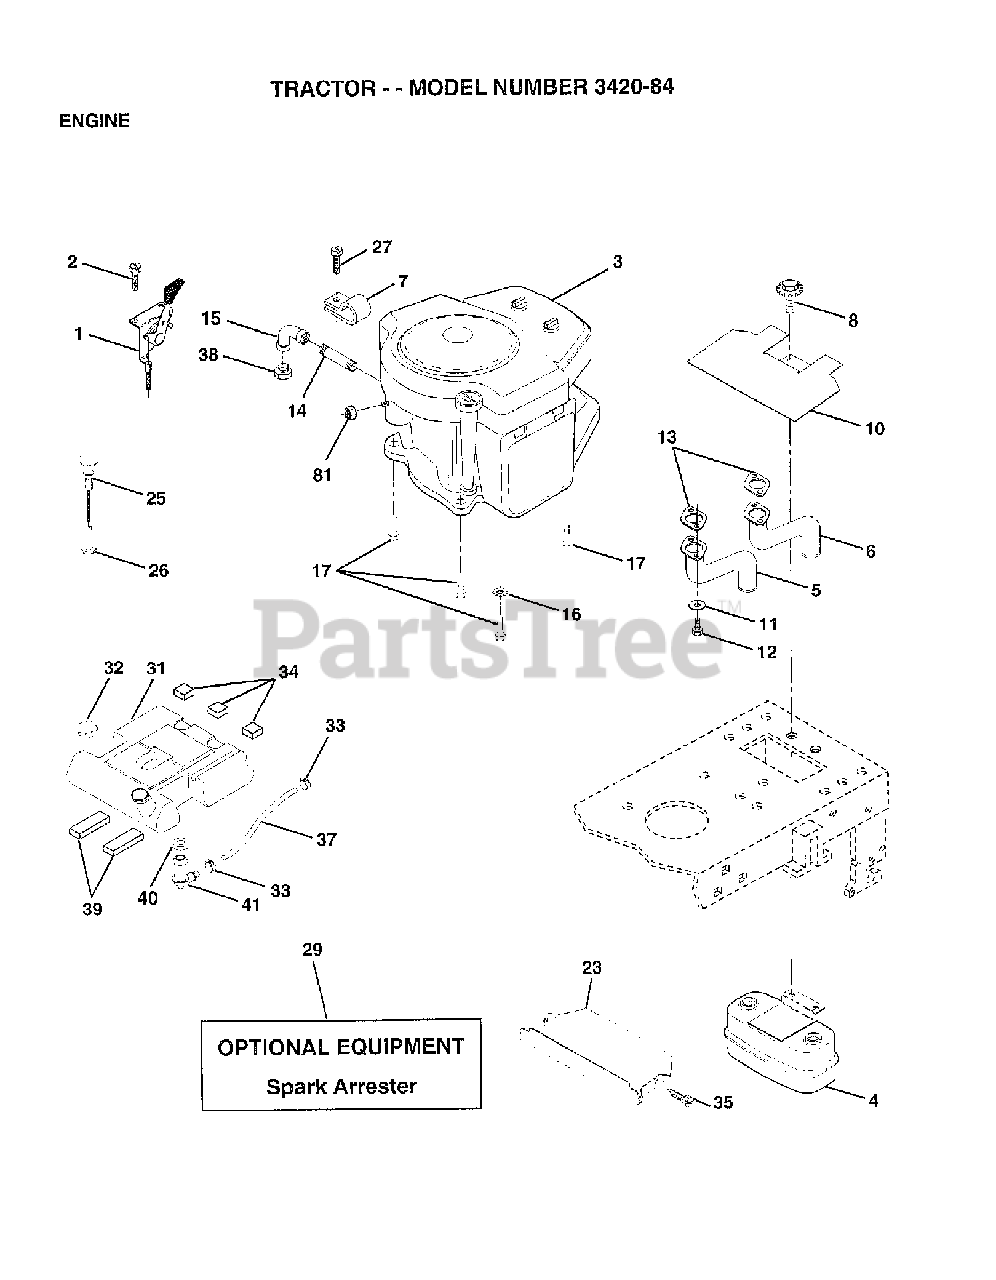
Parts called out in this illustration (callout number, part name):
1	DECK W/DECALS 72" HUS
4	MUFFLER.TWIN.CYL.LOW.TONE
5	EXHAUST ASM. LEFT
6	EXHAUST ASM. RIGHT
10	SHIELD HEAT LT
11	LOCKWASHER
13	GASKET (B&S 692282)
14	NIPPLE, PIPE 3/8NPT X 4-1/2
15	ELBOW
16	LOCKWASHER
23	PROTECTOR
25	CONTROL.CHOKE.51.00.BLK.W/BEND
26	NUT KEPS 3/8 - 24 UNF
27	SCREW.TT.#10-32X.5.3/8.FLANGE
29	KIT.SPARK ARRESTOR(392390 B&S)
31	FUEL TANK
33	HOSE CLAMP
34	PAD-SPACER LT
35	Screw, Lt
37	FUEL LINE
39	PAD IDLER TI
40	BUSHING OUTLET T
41	STEM FUEL TANK
